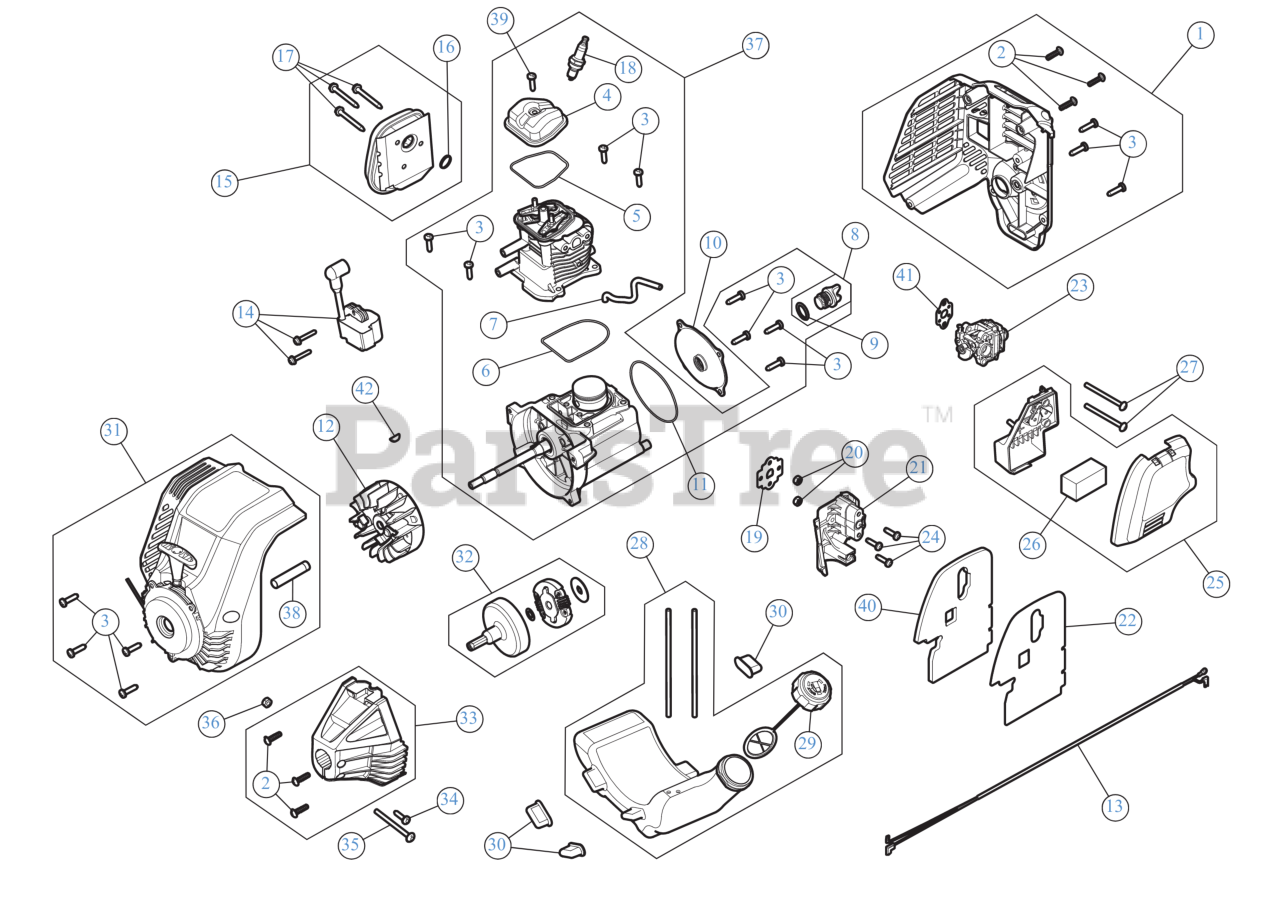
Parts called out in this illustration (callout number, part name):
1	REAR ENGINE COVER
2	SCREW 8-16 x 3/4
3	SCREW M5-0.8 x 19
4	ROCKER COVER
5	O-RING
6	O-RING CYL AC5
7	BREATHER HOSE
8	OIL PLUG
9	RING, OIL PLUG (AC
10	CRANKCASE COVER
11	O-RING CRNKCSE CVR
12	FLYWHEEL ASSEMBLY AC3.1
13	LEAD WIRES
14	MODULE ASSEMBLY
15	MUFFLER ASSEMBLY
16	GASKET/MUFFLER
17	SCREW M5 x 44MM
18	SPARK PLUG 4 CYCL
19	GASKET/INSULATOR
20	NUT 10-32
21	CARB INSULATOR
22	GASKET
23	CARBURETOR
24	SCREW, M5 X18
25	AIR CLEANER COVER
26	AIR FILTER
27	SCREW 10-32X2.5
28	FUEL TANK ASSEMBLY
29	FUEL CAP ASSEMBLY 43MM-6 W/O HOLE
30	FUEL TANK PADS
31	STARTER HOUSING
32	CLUTCH ASSEMBLY
33	CLUTCH COVER
34	SCREW, 8-32 x .312 P
35	SCREW
36	HEX NUT
37	SHORT BLOCK
38	SPACER :2.165"
39	SCR, VALVE COVER
40	HEAT SHIELD
41	CARBURETOR GASKET
42	WOODRUFF KEY #403-.125 x .375
